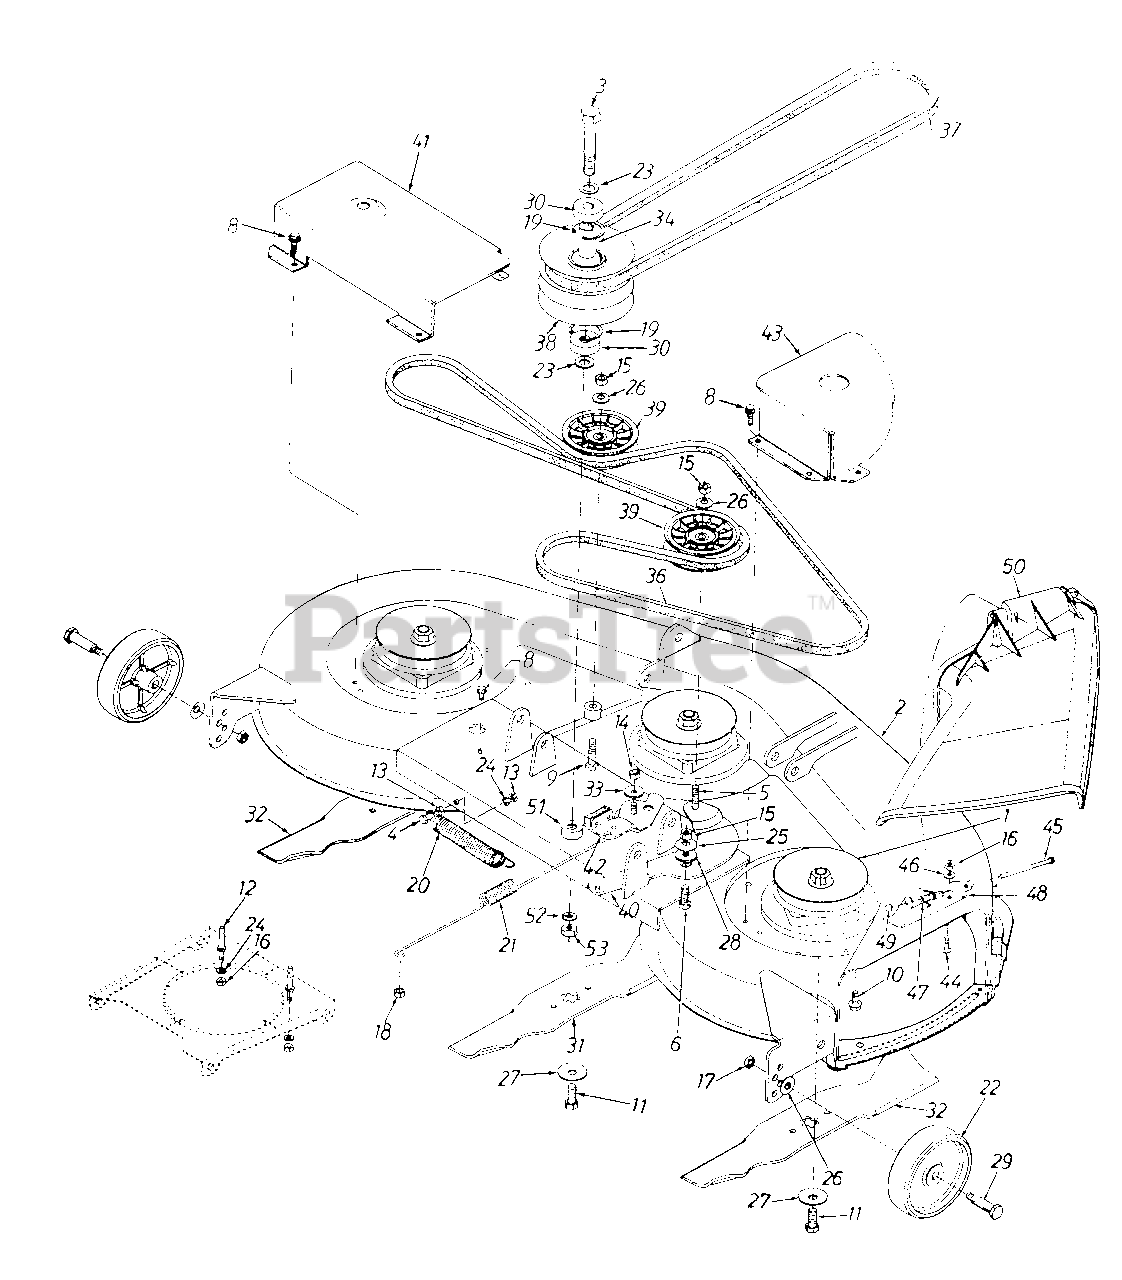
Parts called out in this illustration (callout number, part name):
1	Blade Spindle Ass'y.
4	Hex Bolt 1/4-28 x 1.25" Lg.
5	Hex Bolt 3/8-24 x 1.5" Lg.
6	Mex Bolt 3/8-24 x 1" Lg.
8	Hex Wash. Hd. TT-Tap Scr. 1/4-20 x .5" Lg.
9	Hex Bolt 3/8-24 x 2" Lg.
10	Hex Flange Bolt 5/16-24 x .75" Lg.
11	Hex Patch L-Bolt 7/16-20 x 1" Lg.
12	Belt Guard Pin
13	Hex Nut 1/4-28 Thd.
14	Hex Ins. L-Nut 5/16-24 Thd.
15	Hex Nut 3/8-24 Thd.
16	Hex Nut 1/4-20 Thd.
17	Hex Top Jam Nut 3/8-16 Thd.
18	Hex Patch L-Nut 5/16-18 Thd.
19	Int. Snap Ring
20	Ext. Spring .88" O.D. x 6.17"
21	Ext. Spring .788" O.D. x 15.5"
22	Deck Wheel
23	Fl-Wash. .635" I.D. x 1" O.D. x .06"
24	L-Wash. 1/4" I.D.
25	Bell-Wash. 3/8" x 1.125" x .062"
26	Bell-Wash. 3/8" x .87" x .064"
27	Bell-Washer
28	Shoulder Spacer .625" I.D. x .169"
29	Shld. Bolt .498" x 1.525"
30	Ball Brg. .625" I.D. x 1.574" O.D. x .47"
31	High Lift Blade 14.88" Lg.
32	High Lift Blade 16.28" Lg.
33	Shoulder Spacer
34	Spacer .635" I.D. x .088" 0 D.
36	V-Belt
37	V-Belt
38	Pulley Double Deck 5" O.D.
39	Flat Idler Pulley 3.5 O.D.
42	Deck Brake Brkt. Ass'y.
44	Hex Bolt 1/4-20 x .62" Lg.
45	Hinge Pin
46	Bell-Wash. 1/4" I.D.
47	Torsion Spring
48	Hinge Mtg. Brkt.
49	Push Nut
50	Chute Ass'y. Comp.
51	Spacer .635" I.D. x 1" O.D.
52	L-Wash. 5/8" I.D.
53	Hex Nut 5/8-18 Thd.
